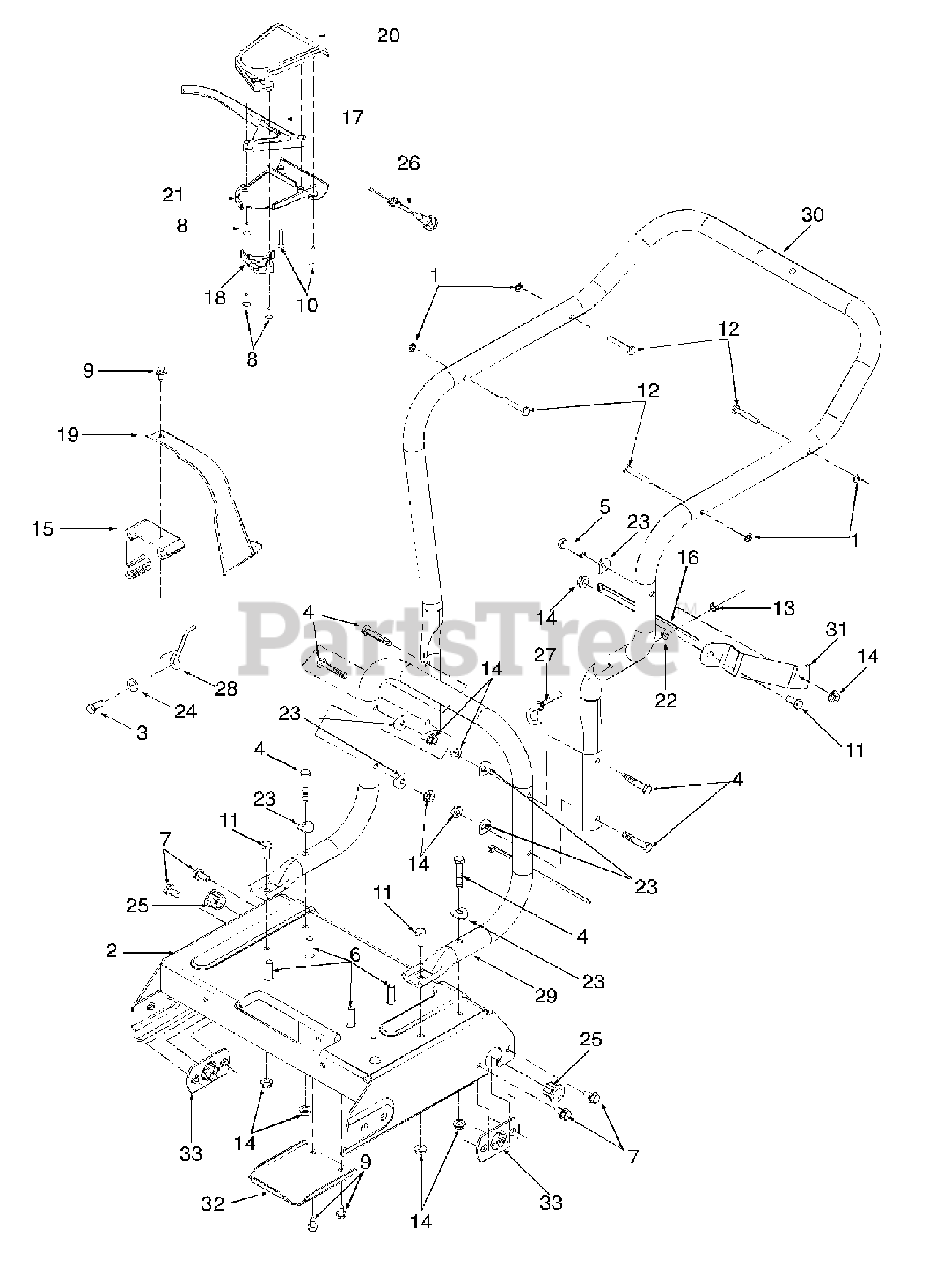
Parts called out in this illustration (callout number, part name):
1	Nut, Push, .25
2	Frame Assembly
3	Screw, Hex Cap, 5/16-24 x .75 GR5
4	Screw, Hex Cap, 5/16-18 x 1.75
5	Screw, Hex Cap, 5/16-18 x 1.5
6	Screw, Hex Wash Hd Tapp, 3/8-16 x 1.25
7	Screw, Hex Wash Hd Tapp, 5/16-18 x .62
8	Screw, Phil Cntrsnk, #10-12 x .75
9	Screw, Hex Wash Hd, 1/4-14 x .62
10	Screw, Phil Cntrsnk, #10-16 x 1.25
11	Screw, Hex Cap, 5/15-18 x .75 GR5
12	Pin, Stud, .250 x 1.75
13	Nut, Hex, 1/4-28
14	Nut, Hex Flange Lock, 5/16-18 GR5
15	Adapter, Engine Mtg
16	Cable Tie
17	Lever, Drive Control
18	Cap, Cable Mtg
19	Belt Cover
20	Upper Clutch Cover
21	Lower Clutch Cover
22	Washer, Lock, 1/4
23	Saddle Washer, .320 x .93
24	Washer, Flat, .344 x .75 x .12
25	Bearing, Flange, .631 ID x .72 OD
26	Cable, Clutch, 56.0
27	Eye Bolt
28	Belt Keeper
29	Handle, Lower
30	Handle, Upper
31	Bracket, Chute Stabilizing
32	Transmission Cover
33	Bracket, Axle
